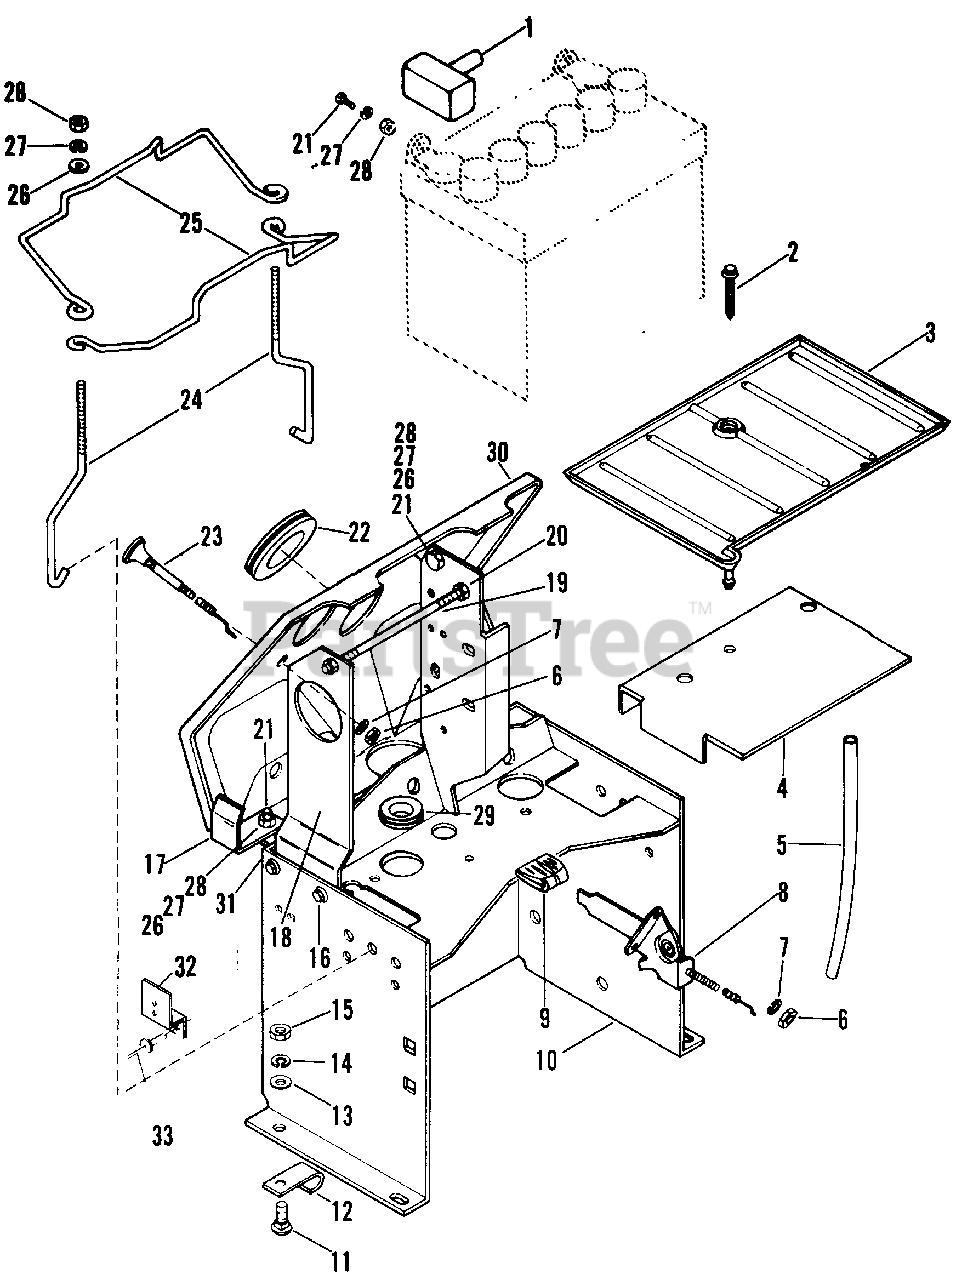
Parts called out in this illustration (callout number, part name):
1	Insulator
2	Screw, Tapping #12-14 x 1.50 OVHPL
3	Battery Tray
4	Battery Stand
5	Hose
6	Nut, #10-24 Hex
7	Washer, Lock No. 10 SP
8	Throttle Control
9	Knob
10	Dash Support
11	Bolt, Carriage 5/16-18 x .75
12	Clip
13	Washer, Flat .406 x .812 x .065
14	Washer, Lock 3/8 SP Heavy
15	Nut, Hex 5/16-18
16	Taptite, 1/4-20 x .50
17	Clip
18	Hourmeter Mounting Plate
19	Brace Rod
20	Nut, Lock 1/4-20
21	Bolt, Hex 1/4-20 x .875
22	Grommet
23	Choke Control
24	Tie Down
25	Hold Down
26	Washer, Flat .281 x .625 x .065
27	Washer, Lock 1/4 Reg.
28	Nut, Hex 1/4-20
29	Grommet
30	Dash
31	Screw, Tapping #10-16 x .50 HWHPL
32	Bracket, Hood Latch Mtg.
33	Rivet, Pop Domed 1/8 x .294
NS	Dash Decal
NS	Instruction Decal
NS	Rear Implement Decal
